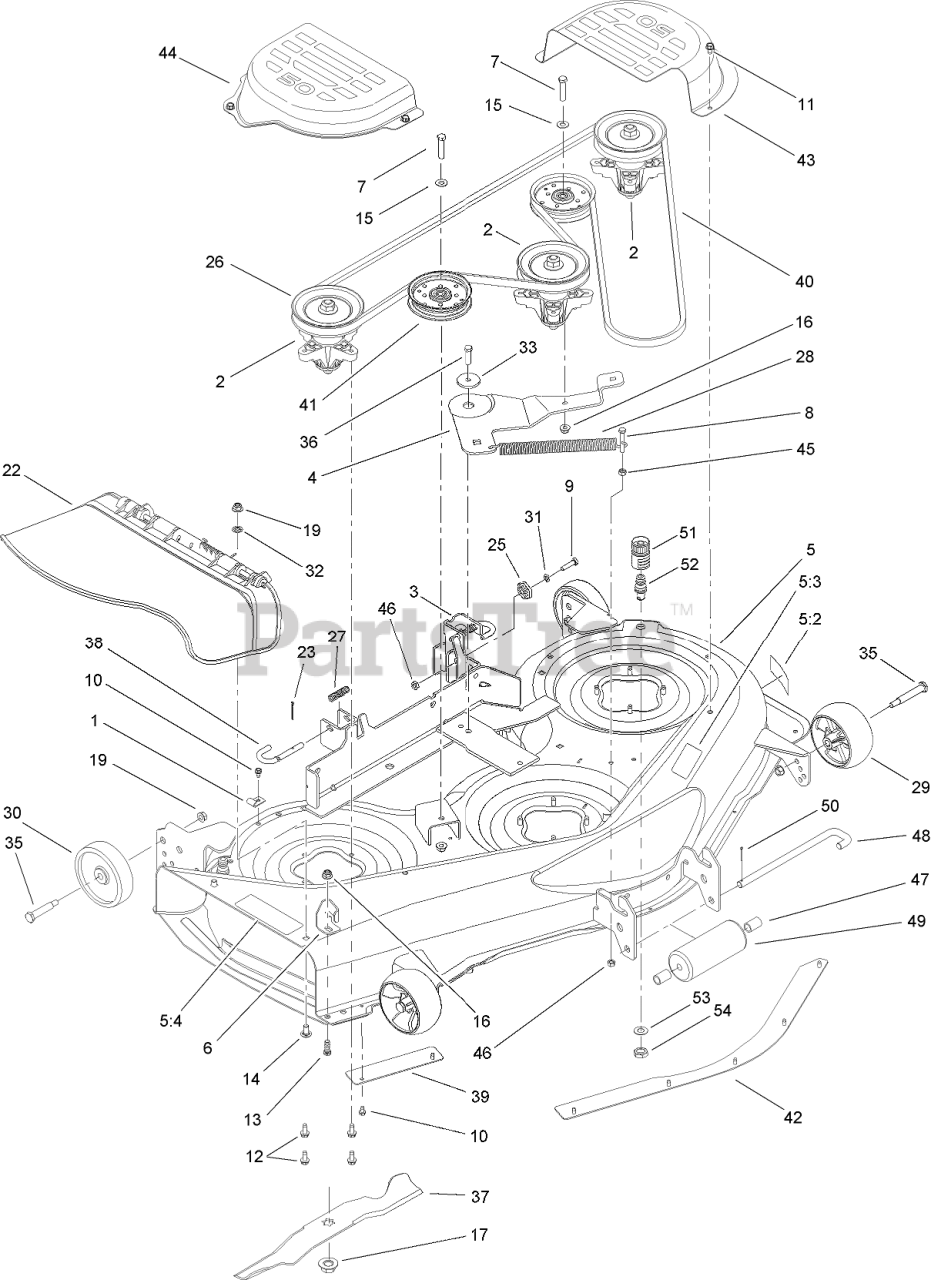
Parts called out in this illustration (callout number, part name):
1	BRACKET-RETAIN, HOOK
2	SPINDLE ASM
3	LH HANGER BRACKET ASM
4	BRACKET-IDLER
5	DECK AND DECAL ASM
5:2	DECAL-DANGER, DECK
5:3	DECAL-BELT ROUTING, DECK
5:4	DECAL-DANGER
6	STOP-CHUTE
7	SCREW-HH
8	SCREW-HH, TAP
9	SCREW-HH
10	SCREW-HWHTF
11	SCREW-HH, TAP
12	SCREW-HWH
13	SCREW-HH
14	BOLT-CARR
15	WASHER-FLAT
16	NUT-LOCK, FLANGE
17	NUT-LOCK, FLANGE
19	NUT-LOCK, FLANGE
22	CHUTE ASM
23	PIN-COTTER
25	GEAR-ADJUSTMENT, DECK
26	PULLEY-DECK
27	SPRING-COMPRESSION
28	SPRING-EXTENSION
29	WHEEL-DECK, FRONT
30	WHEEL-DECK, REAR
31	WASHER-LOCK
32	RETAINER-BOLT
33	SPACER-SHOULDER
35	BOLT-SHOULDER
36	SCREW-HH
37	BLADE-17.90 INCH
38	PIN-HANDLE, DECK RELEASE
39	SKIRT-RH
40	BELT-V, TYPE B
41	PULLEY-IDLER
42	SKIRT-CENTER
43	COVER-BELT, LH
44	COVER-BELT, RH
45	NUT-HEX
46	NUT-LOCK, FLANGE
47	SPACER
48	PIN-ROLLER
49	ROLLER
50	PIN-COTTER
51	ADAPTER-NOZZLE, WATER
52	NOZZLE-WATER, DECK
53	WASHER-LOCK
54	NUT-HEX
